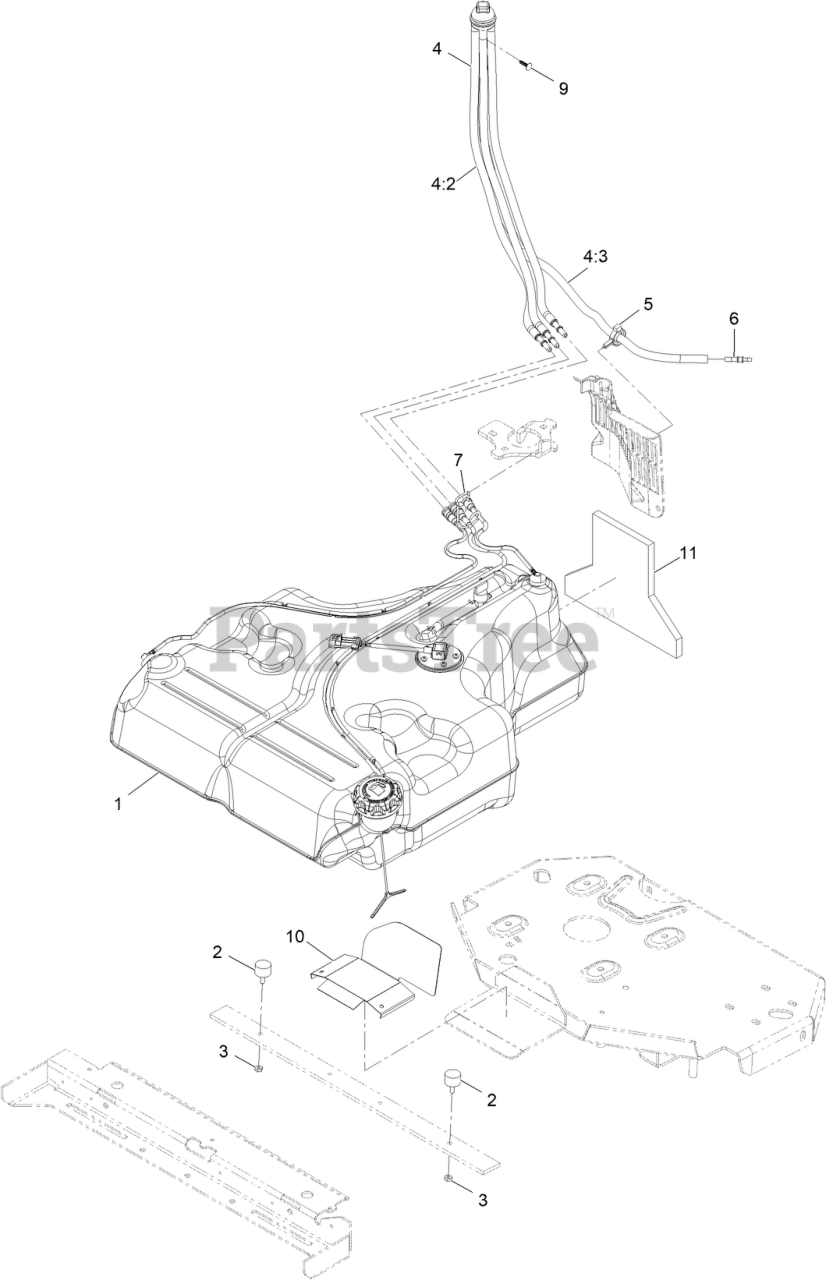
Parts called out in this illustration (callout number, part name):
1	FUEL TANK ASM
2	BUMPER
3	NUT-JAM
4	FUEL MANIFOLD VENT ASM
4:2	HOSE-FUEL
4:3	HOSE-FUEL
5	CLAMP-HOSE
6	BARB-FUEL
7	RETAINER-LINE, VAPOR
9	PLUG-PLASTIC
10	GUARD-EXHAUST
11	INSULATION-FOAM, FUEL TANK
